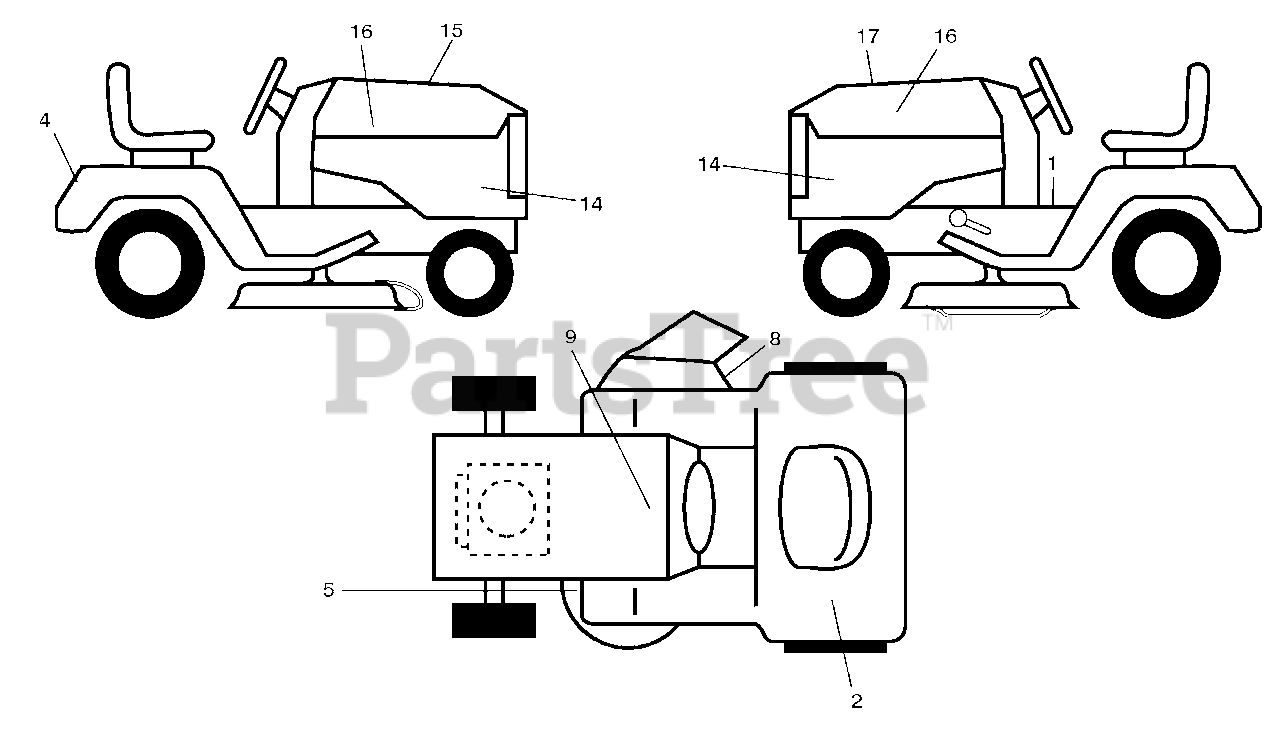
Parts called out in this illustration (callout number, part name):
1	Decal, Warning
2	Decal, Ethanol E85
4	Decal, Fender
5	Decal, Caution
8	Decal, Mower Sch.
9	Decal, Battery Dnge/Poi
14	Decal, Panel Side
15	Decal, Warning Customer Resp.
16	Decal, Hood Logo
17	Decal, Replacement
18	Decal, Bypass
19	Pad, Footrest, LH
20	Pad, Footrest, RH
